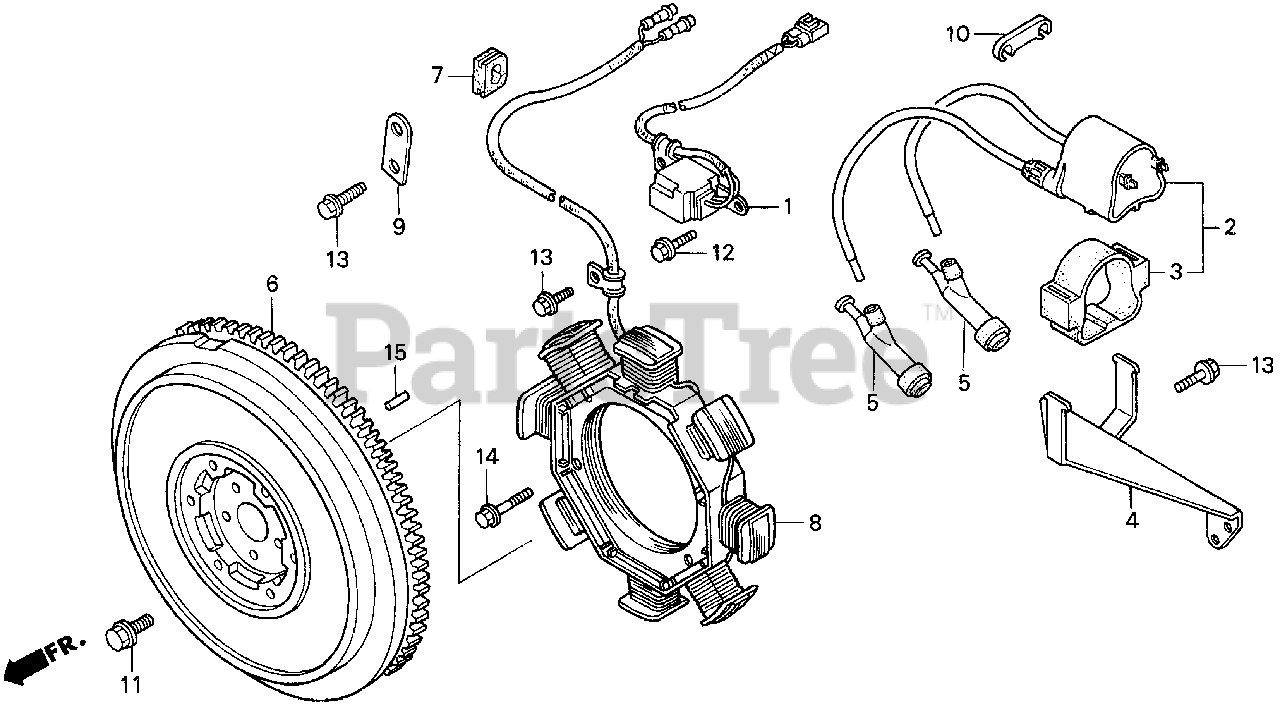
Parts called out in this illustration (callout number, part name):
1	COIL ASSY., PULSER
2	COIL ASSY., IGNITION
3	SUSPENSION, IGNITION COIL
4	BRACKET, IGNITION COIL
5	CAP ASSY., NOISE SUPPRESSOR (NICHIWA Y-EZ RTFM256)
7	GROMMET, WIRE
8	COIL ASSY., CHARGE
9	BRACKET, WIRE HARNESS CLIP
10	CLAMP, WIRE
11	BOLT, HEX. (10MM)
12	BOLT, FLANGE (5X16)
13	BOLT, FLANGE (6X14)
14	BOLT, FLANGE (6X25)
15	PIN B, DOWEL (6X10)
